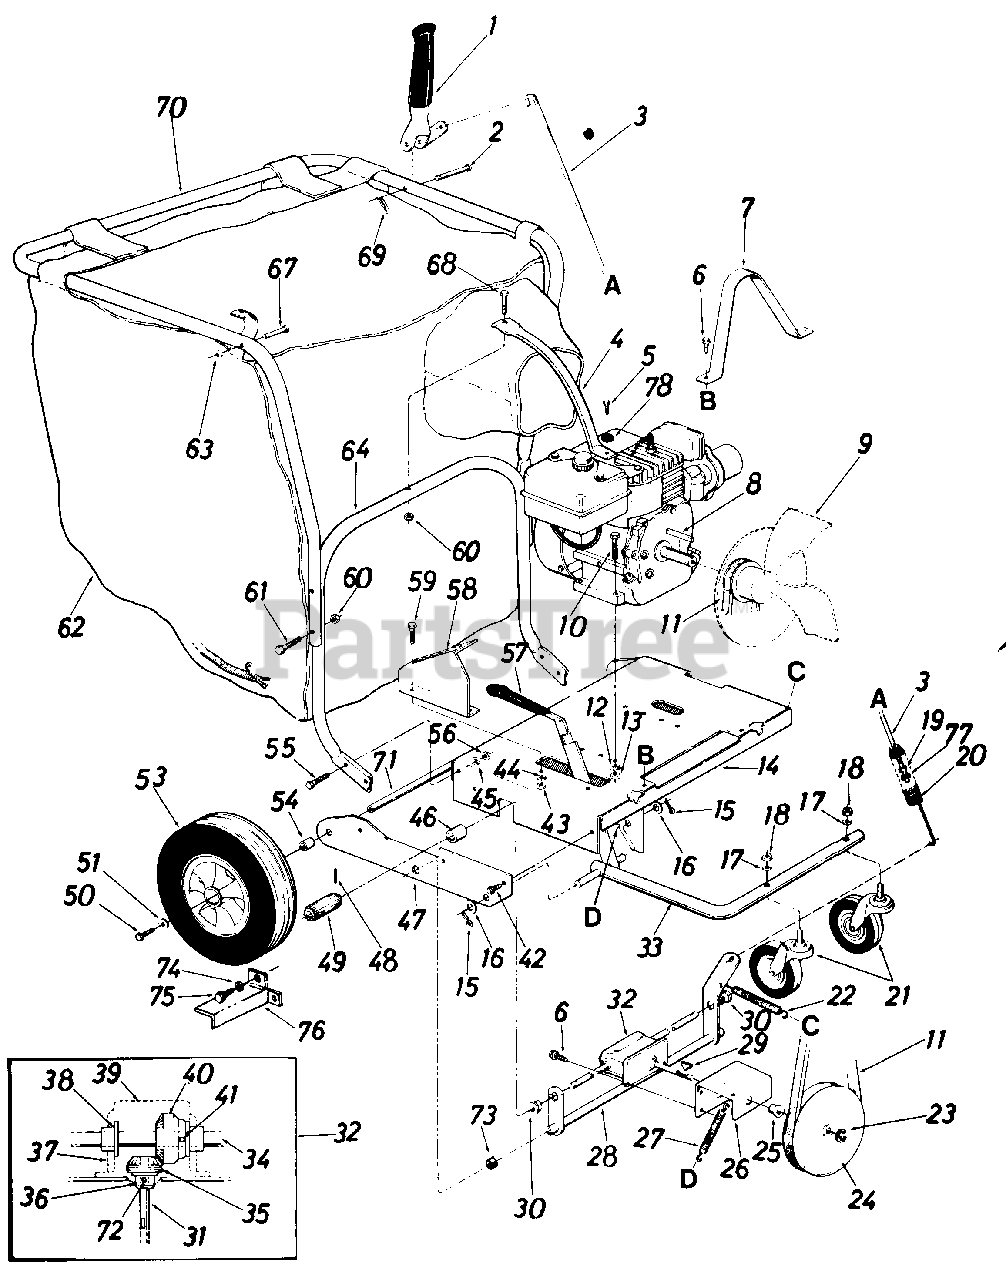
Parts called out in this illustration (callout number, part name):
1	GRIP ASSY-CLUTCH
2	PIN-CLEVIS
3	ROD-LOCKOUT
4	BRACE-HANDLE PAINTED
6	SCREW-HEX WASH HD
9	PLATE ASSY-VANE
10	SCREW-HEX 5/16-18 X 1.50
11	BELT-V 1/2 X 26
12	WASHER-LOCK-5/16
13	NUT-HEX 5/16-18
14	FRAME-ENG MTG
15	PIN-COTTER-1/8 DIA X 1.00
16	WASHER-FL-.640ID X 1.24OD X .06HDN
17	WASHER-LOCK-1/2
18	NUT-HEX 1/2-13
19	NUT-HEX CENTER L-1/4-20
21	WHEEL ASSY-CASTER
22	SPRING-EXTENSION
23	RING-E FOR .500 SHAFT
25	BEARING-FLANGE
28	BRACKET ASSY-CLUTCH
29	KEY-WOODRUFF #2-3/32X1/2 DIA-HDN
30	BEARING-HEX FLANGE
31	SHAFT-PINION
32	GEAR CASE ASSY-COMP
33	ARM ASSY-CASTER
34	SHAFT-DRIVE-22IN-HW
35	PINION-14T
36	BEARING-FLANGE .503 ID
37	KIT-GEAR BOX ASSY
38	BEARING-FLANGE
39	COVER-GEAR BOX
40	GEAR-BEVEL-.62 ID 28T
41	PIN-SPRING SPIR 3/16 X 1.25
42	SCREW-HEX HD TAP
43	NUT-HEX 5/16-18
44	WASHER-LOCK-5/16
45	WASHER-LOCK-5/16
46	SPACER
49	PINION-DRIVE
50	SCREW-HEX 5/16-24 X .62 SPEC PLAST
51	WASHER-FL-.344 ID X .88 OD X .063
53	WHEEL ASSY W/TIRE
55	SCREW-HEX 5/16-18 X .75
56	NUT-HEX 5/16-18
57	GRIP-FL BAR-END
58	PLATE-INDEX
59	SCREW-HEX 5/16-18 X .75
60	NUT-HEX CENTER L-1/4-20
61	SCREW-HEX 1/4-20 X 1.75
62	BAG-VACUUM FELT
63	NUT SPECIAL
64	HANDLE-LOWER
67	PIN-STUD
68	SCREW-HEX 1/4-20 X 1.75
69	PIN-INTERN COT
70	HANDLE-UPPER-BLACK
72	PIN-SPRING ROLL 5/32 X 1.12
74	WASHER-SPRING.270 ID X.51 OD X.030
75	SCREW-HEX B-TAP 1/4 X .38
78	WASHER-BELL .337 X .867 X .057
